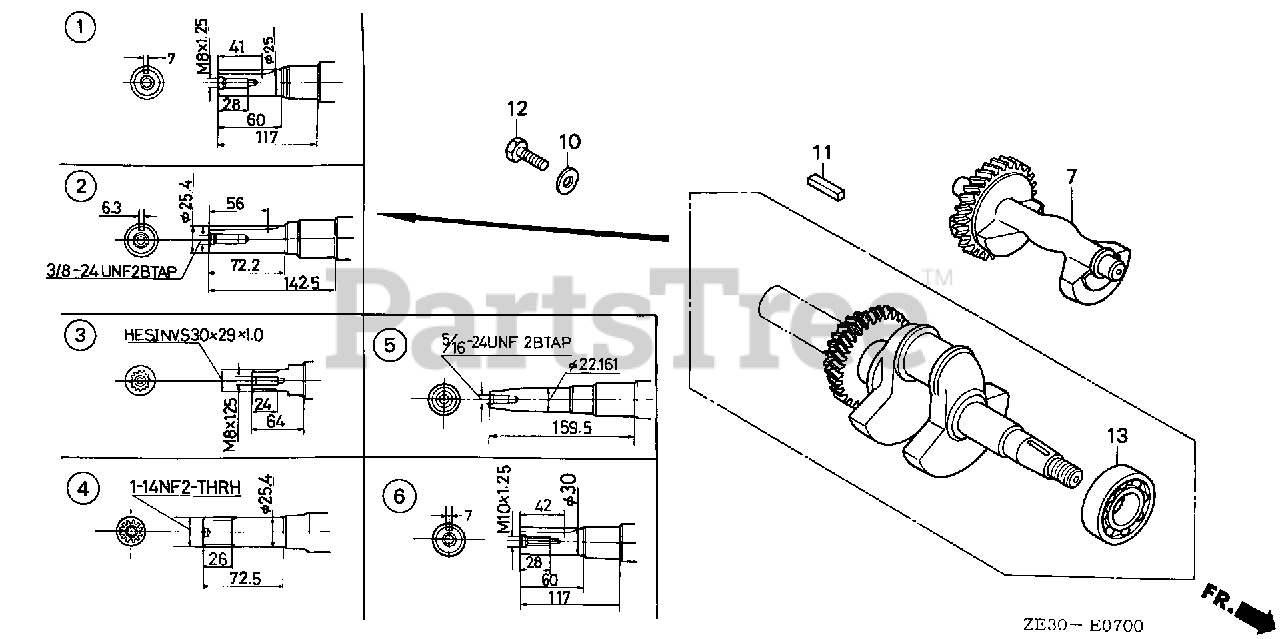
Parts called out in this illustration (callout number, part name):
4	CRANKSHAFT (NOT AVAILABLE)
4	CRANKSHAFT
7	WEIGHT, BALANCER (NOT AVAILABLE)
7	WEIGHT, BALANCER
13	BEARING, RADIAL BALL (6207)
